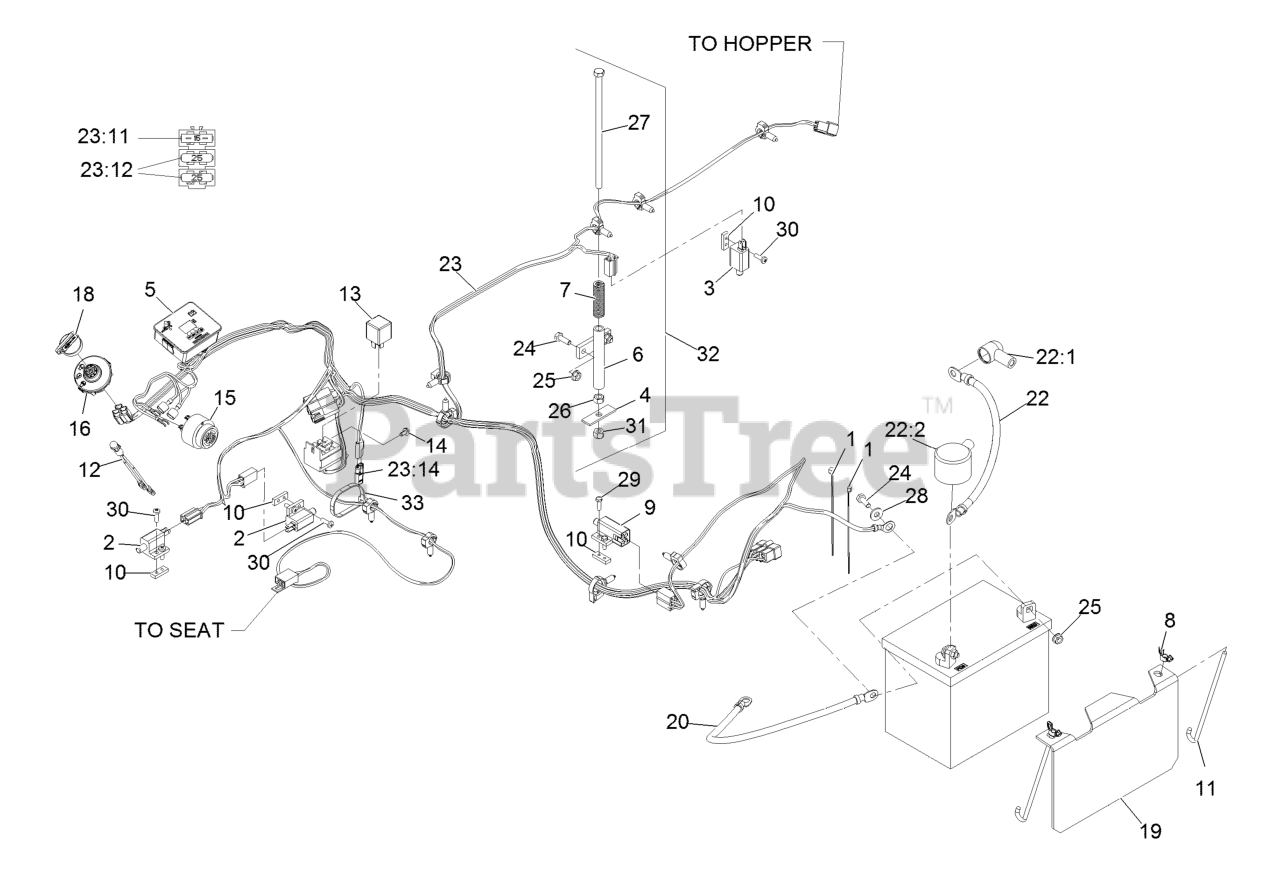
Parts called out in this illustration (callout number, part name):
1	TIE-CABLE
2	SWITCH-OPEN, NORMALLY
3	SWITCH-CLOSED, NORMALLY
4	PLATE-SWITCH, SEAT
5	HOUR METER ASM
6	MOUNT-SPRING, SEAT
7	SPRING-SWITCH, SEAT
8	WINGNUT
10	PLATE-TAPPED
11	BOLT-HOLDDOWN
12	INDICATOR-LED, RED
14	SCREW-HWH
15	ALARM-TONE, DUAL
18	KEY-IGNITION
19	HOLD DOWN-BATTERY
20	CABLE-BATTERY, NEGATIVE
22	CABLE-BATTERY, POSITIVE
22:1	INSULATOR-SOLENOID
22:2	INSULATOR-BATTERY
23	HARNESS-WIRING
23:11	FUSE-BLADE, 15 AMP
23:12	FUSE-BLADE, 25 AMP
23:14	CAP-PLUG
24	SCREW-HH
26	NUT-HEX
27	SCREW-HH
28	WASHER-FLAT
30	SCREW-PPH
31	NUT-LOCK, NI
32	HOPPER SWITCH ACTUATOR AS
33	TIE-PLASTIC
